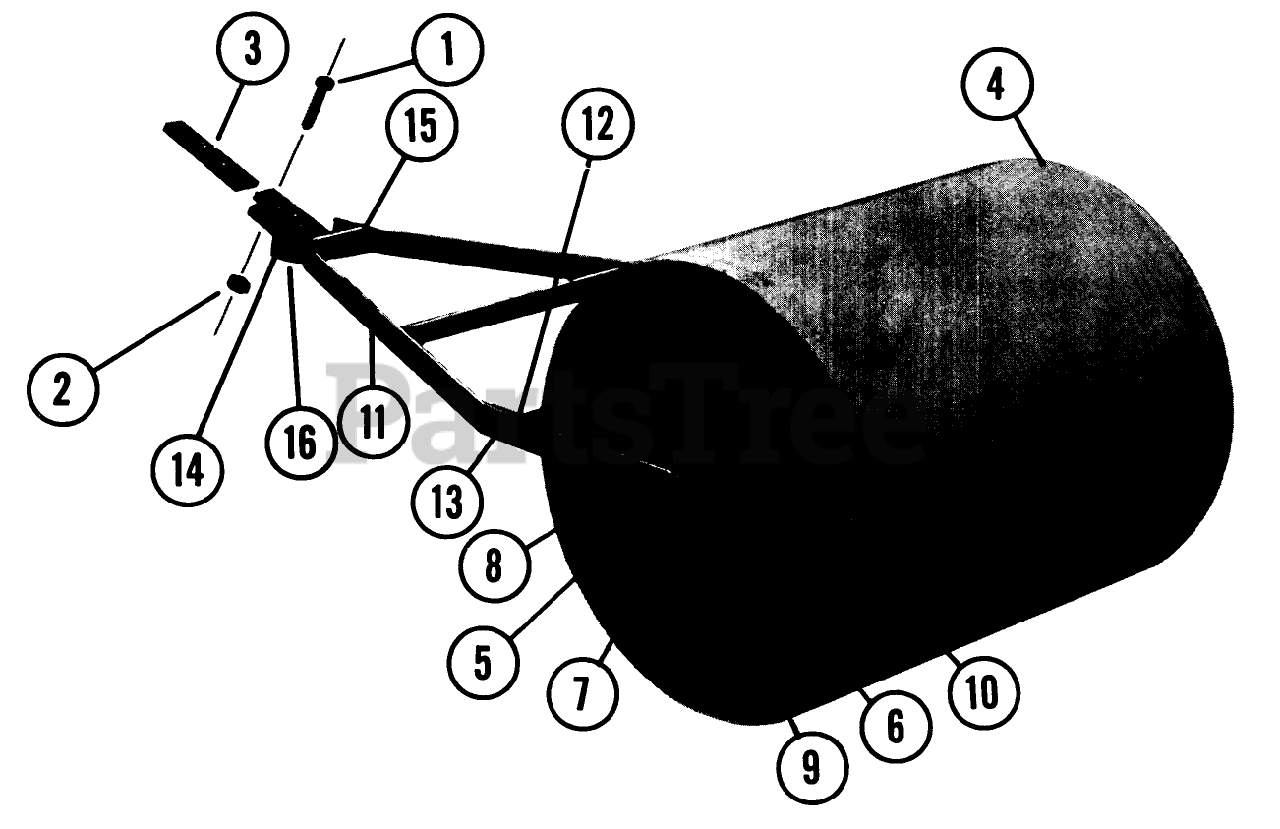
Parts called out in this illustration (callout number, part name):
1	1077 WH '67 TRACTOR
3	Hitch Bar
4	Tank #12, 18 x 24
5	Ball Bearing
6	Bearing
7	Washer
8	Stove Bolt w/Nut
9	Cotter Pin
10	Pipe Plug
11	Frame
12	Scraper Bar
13	Stove Bolt w/Nut
14	Swivel Assembly
15	Stove Bolt w/Nut
16	Cotter Key
